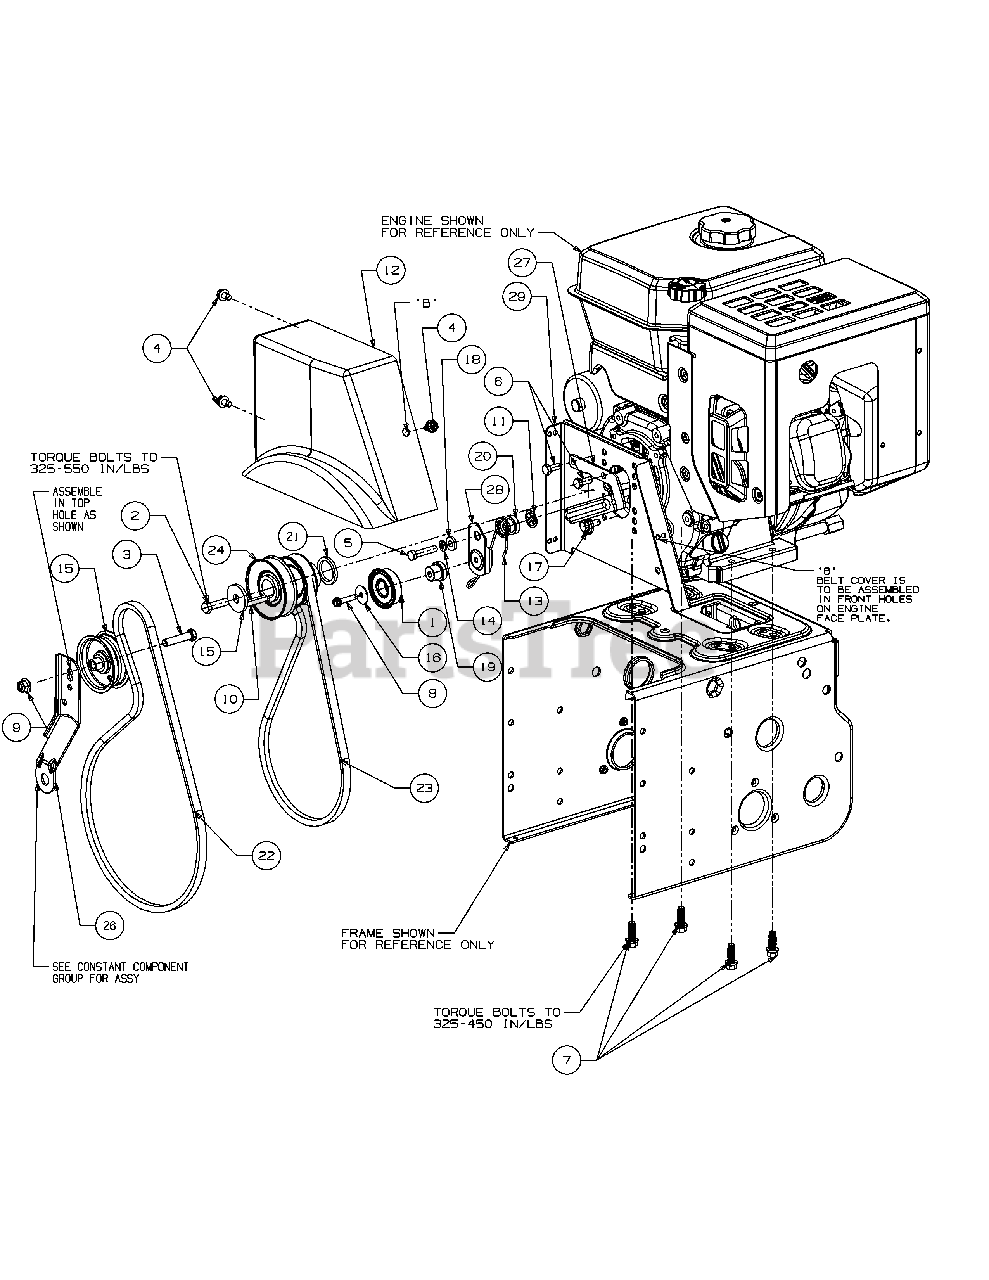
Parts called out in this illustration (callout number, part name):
1	Pulley Asm:Idler
2	Screw 3/8-24X1.25
3	Screw-Hex 3/8-16 X
4	Screw-Tap 5/16-18X
5	Screw-5/16-24 X 1.
6	Screw-Cap Lock 5/1
7	Screw-Hex
8	Screw-Hex 1/4-20 X
9	Nut-Flange Lk.Nylo
10	Key-Sq 1/4 X 1.50
11	Nut-Push On
12	Cover-Belt
13	Spring-Torsion
14	Washer-Lock 5/16
15	Washer-Flat .45 X
15	Pulley, Flat Idler, 2.75 OD
16	Washer-Flat
17	Screw-Shoulder
18	Spacer-Shoulder
19	Spacer:Shoulder
20	Spacer-Shoulder .3
21	Spacer 1.155 X 1.
22	Belt-V Type 1/
23	Belt-V Type 3/8
24	Pulley-Engine
26	Bracket-Idler Auge
28	Bracket-Idler
